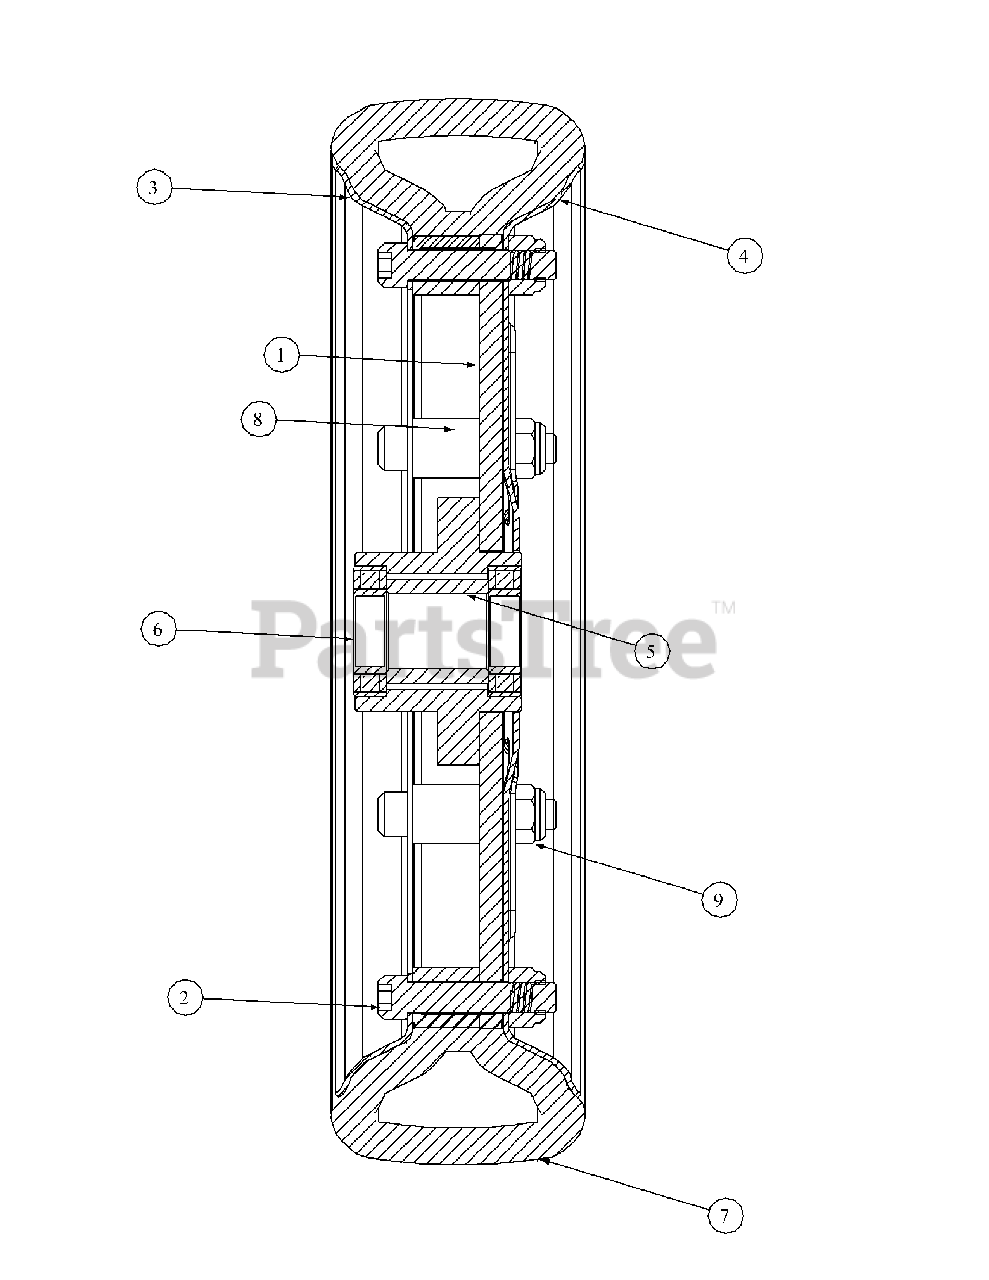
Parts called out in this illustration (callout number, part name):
1	non serviceable part
2	non serviceable part
3	non serviceable part
4	non serviceable part
5	Spacer, .635 ID x .86 Long
6	Ball Bearing, 15mm x 28mm x 7mm
7	Tire, 9 x 2.125
8	non serviceable part
9	Hex Lock Nut, 1/4-20
